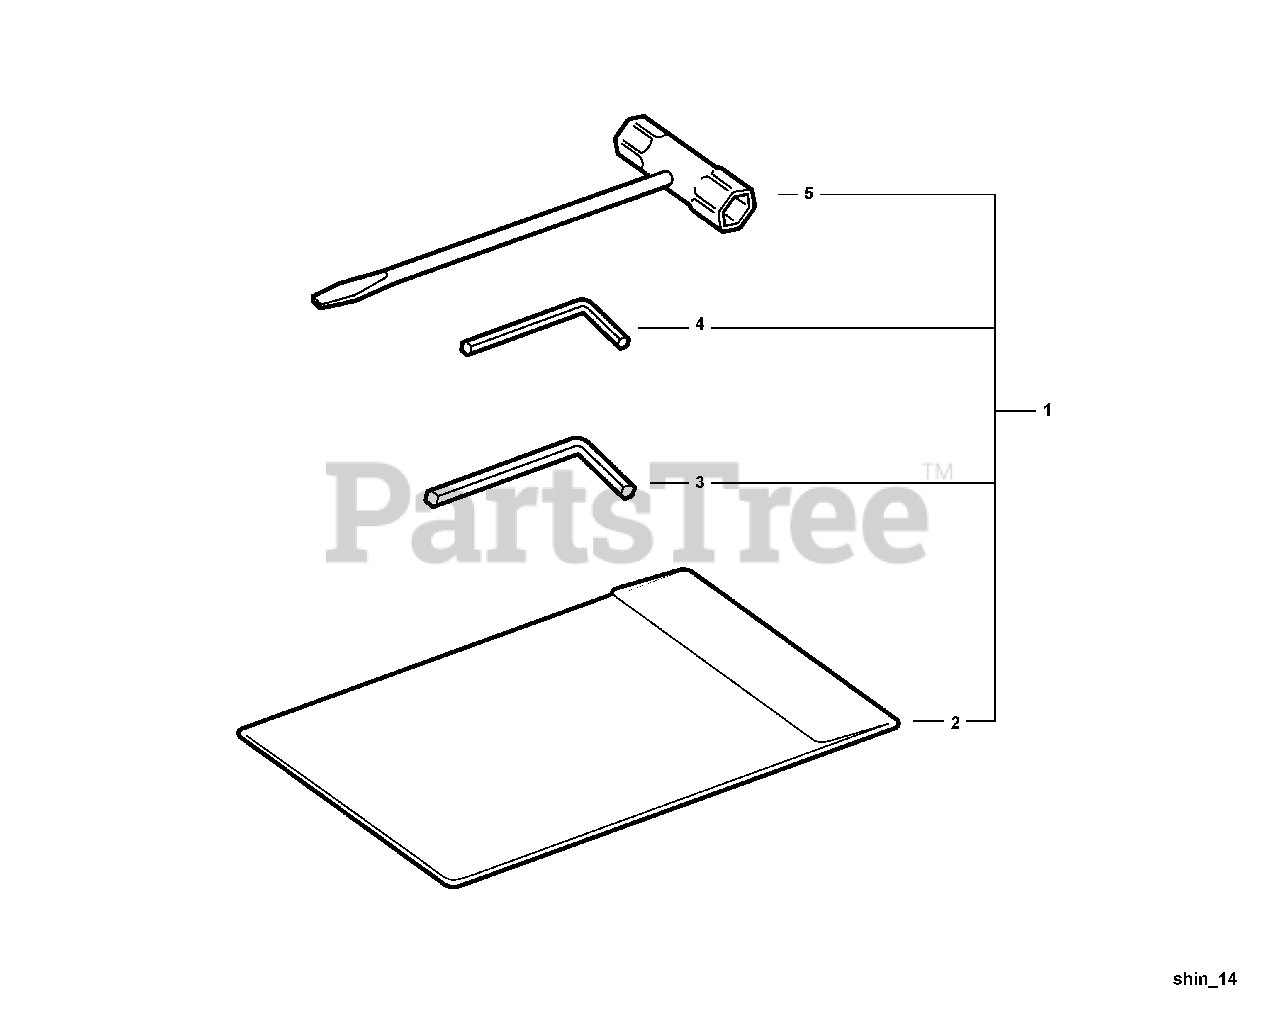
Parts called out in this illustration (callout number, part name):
1	TOOL KIT
2	HEX KEY - 3mm
3	HEX KEY - 4mm
4	T-WRENCH - 13X19mm
5	BAG, TOOL
